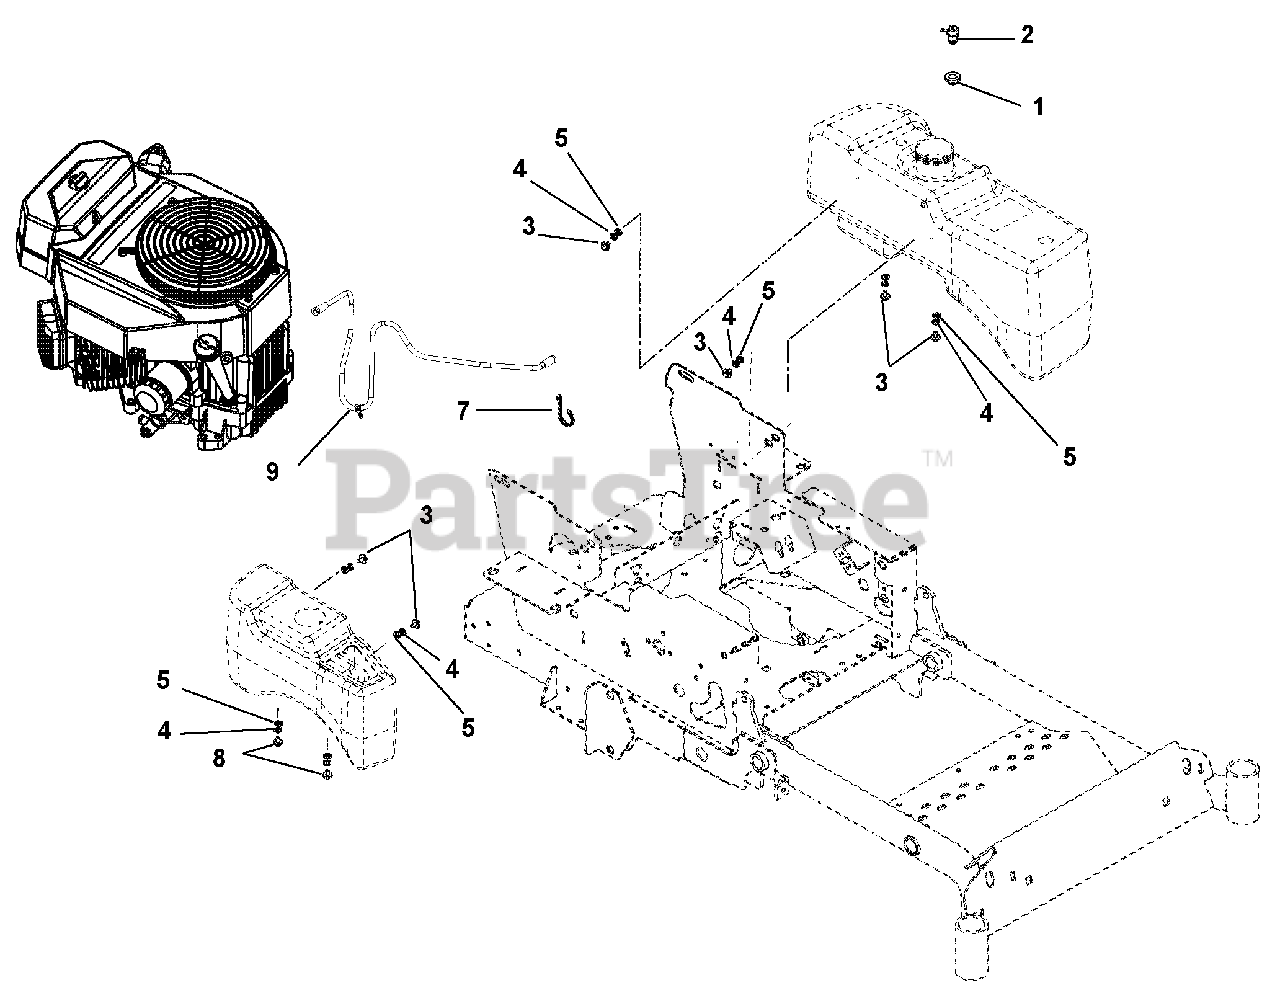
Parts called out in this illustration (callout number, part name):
2	Valve
3	Bolt, .31-18 x .62
4	Washer, Locking .31 x .078 Regular
5	Washer, Flat Steel .38 x .875 x .083
6	Cupholder, Snap-in 3.75 O.D.
7	Tie, Cable LG 5.50
8	Screw, Plastite .25-10 x .75 YZ
9	Line, ZTHD Kawasaki Evap
